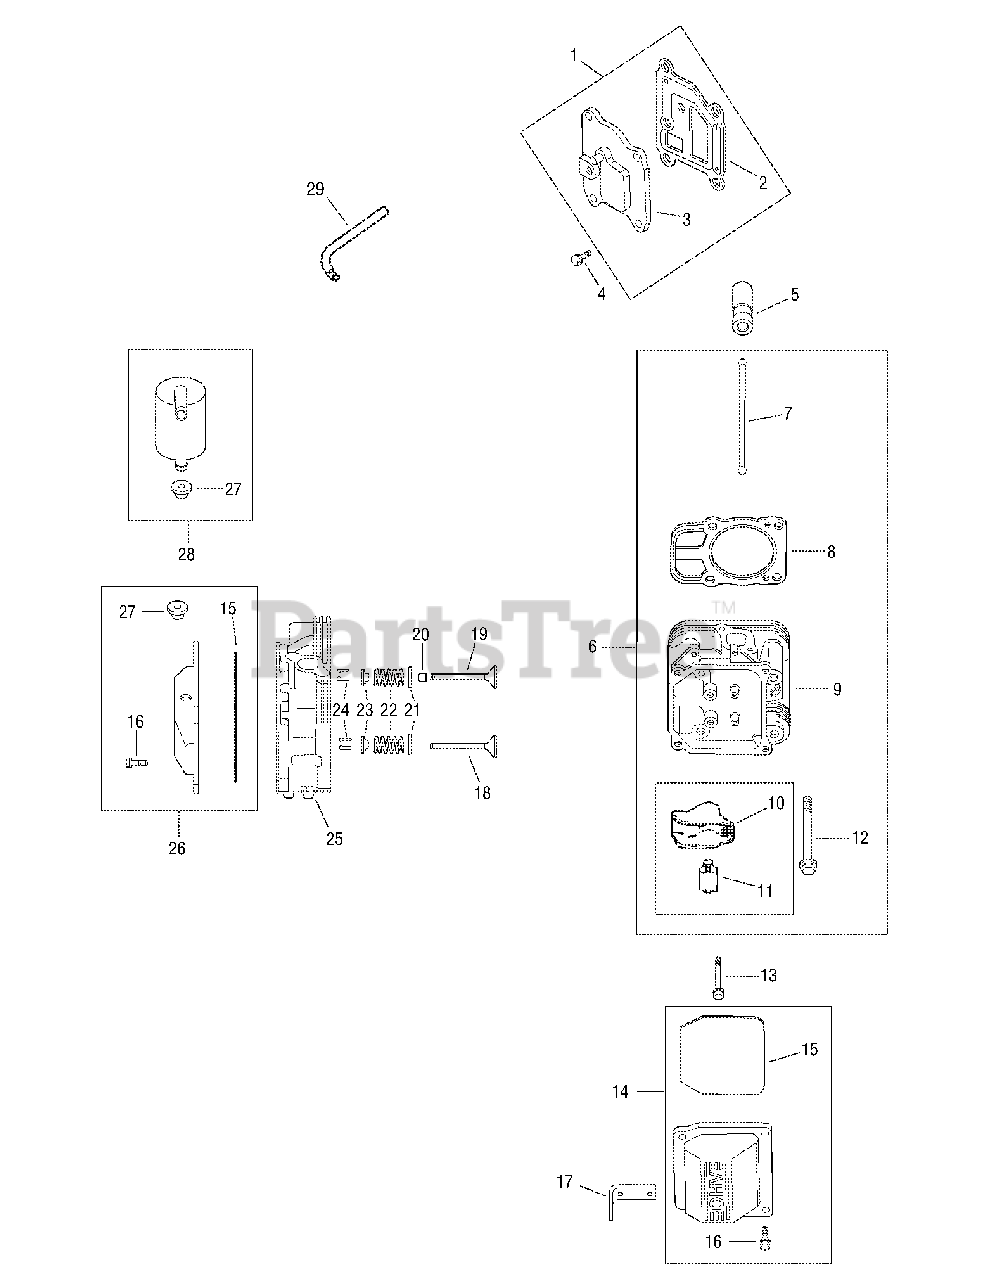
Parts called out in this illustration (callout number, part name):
1	Kit, breather cover w/ gasket (Includes 2,3)
2	Gasket, breather
3	Cover, breather
4	Screw, hex. flange M6 x 1.0 x 20
5	Lifter, valve
6	Kit, valve train (Includes 7,10,11)
8	Kit, cylinder head gasket (Includes head mounting hardware)
9	Head assembly, #2 cylinder
11	Pivot, rocker arm
12	Screw, hex. flange
13	Screw, hex. flange M6 x 1.0 x 34
14	Kit, valve cover – plain (Includes 15,16)
15	O-Ring
16	Screw, hex. flange M6 x 1.0 x 30
17	Strap, lifting
18	Valve, exhaust (Std.)
19	Valve, intake (Std.)
20	Seal, valve stem
21	Retainer, spring
22	Spring, valve
23	Cap, valve sprin
24	Kit, retainer
25	Head assembly, #1 cylinder
26	Kit, valve cover – breather (Includes
27	Grommet, rubber
28	Kit, breather separator (Includes 27)
29	Hose, breather
